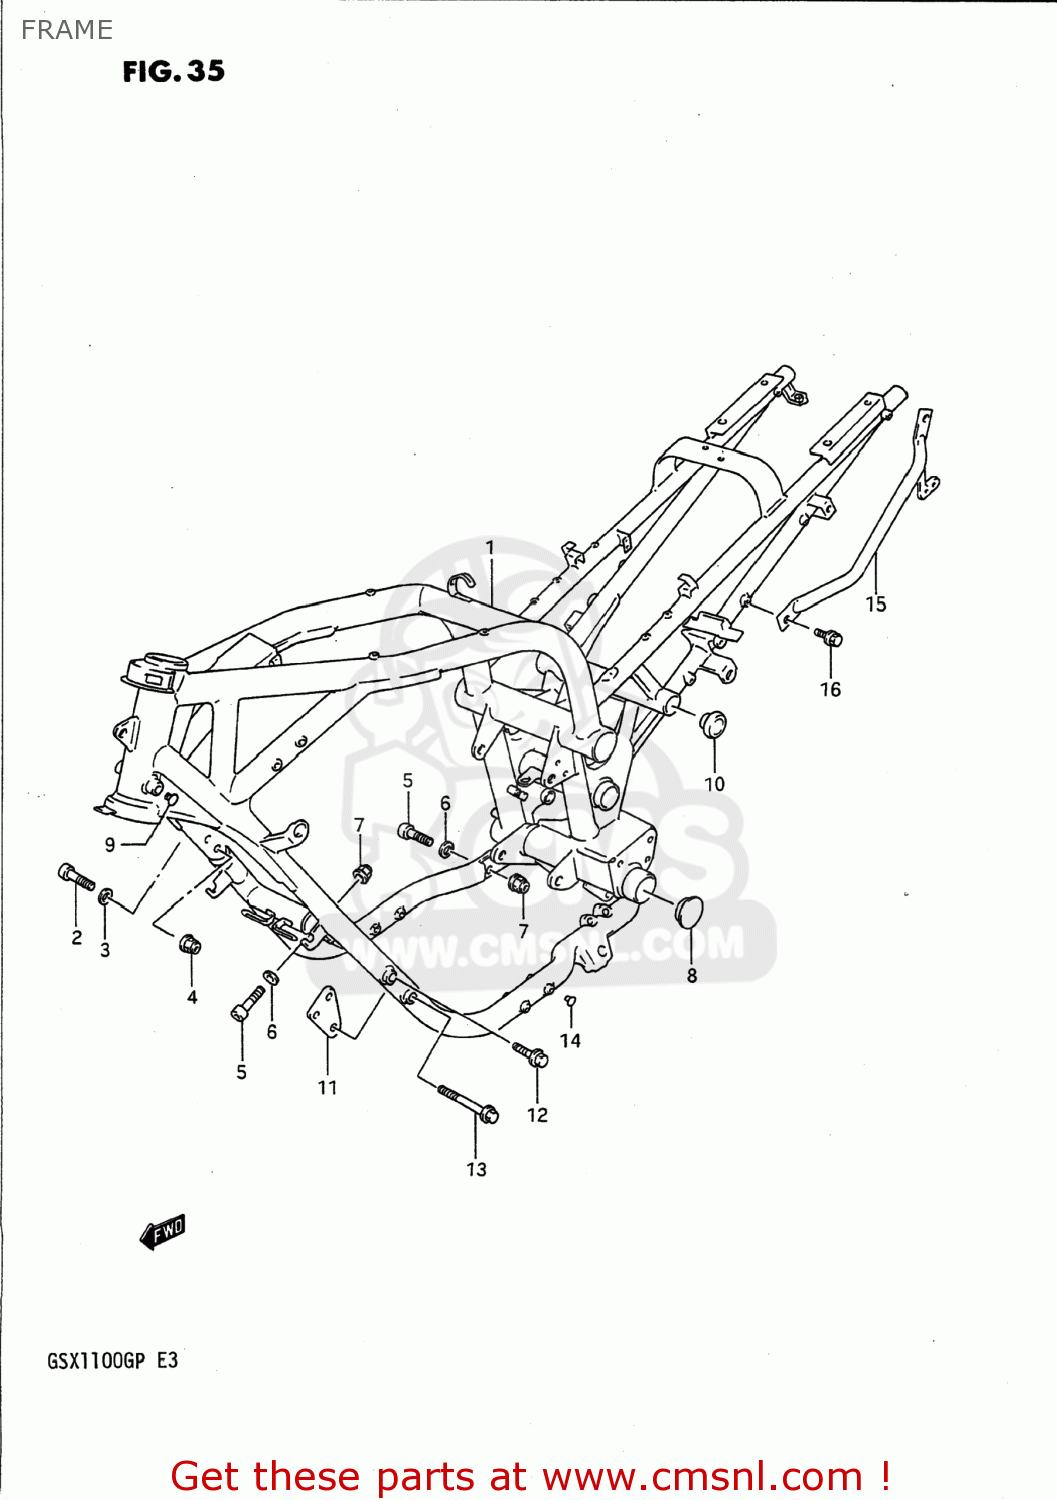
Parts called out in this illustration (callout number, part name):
1	FRAME
2	BOLT 10X38
3	WASHER
4	NUT 10MM
5	BOLT(10X33)
6	WASHER
7	NUT 10MM
8	CAP,BODY TUBE
9	CAP(OD:14)
10	CAP(OD:45)
11	PLATE,ENGINE MOUNTING NO.1
12	BOLT
13	BOLT 8X60
14	CAP(OD:12)
15	GRIP COMP,REAR,LEFT
16	BOLT 8X16
